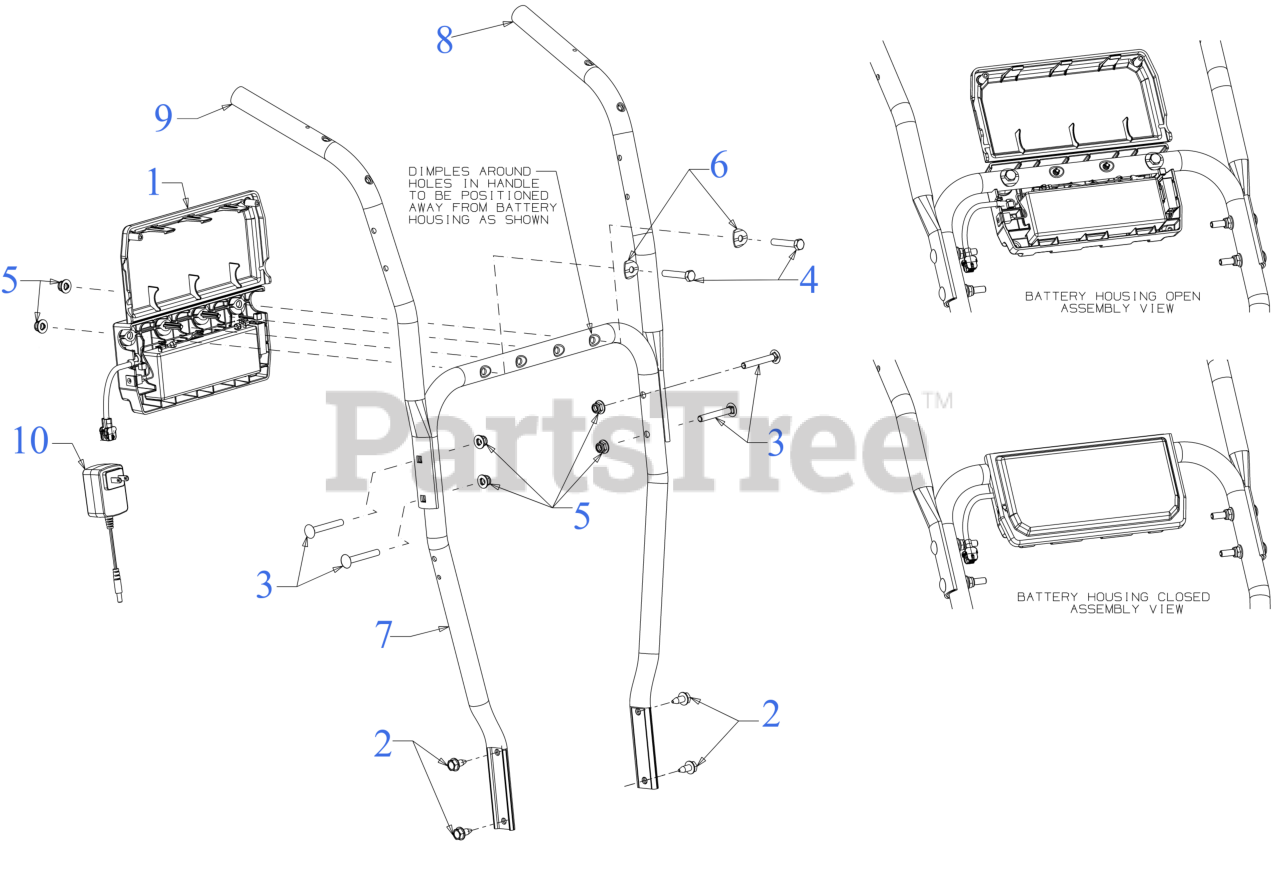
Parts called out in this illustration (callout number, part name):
1	BATTERY (12V 2.6AH)
2	SCREW 5/16-18 x .750
3	BOLT 5/16-18 x 2.50 GR1
4	SCREW 5/16-18 x 1.75 GR5
5	FLANGE LOCK NUT 5/16-18
6	SADDLE WASHER
7	LOWER HANDLE
8	UPPER HANDLE (LH)
9	UPPER HANDLE (RH)
10	BATTERY CHARGER
